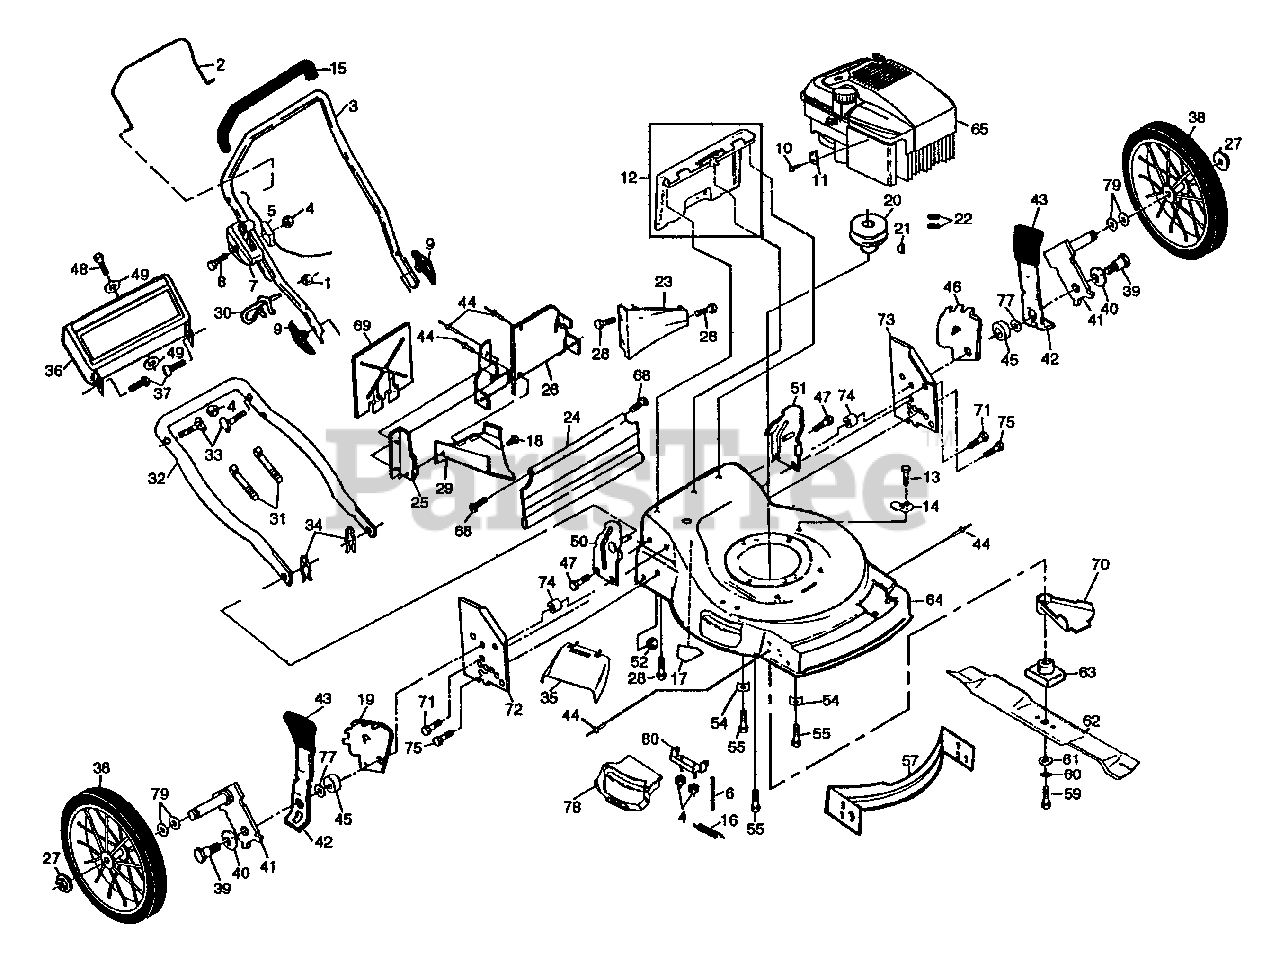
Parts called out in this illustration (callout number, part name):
1	Locknut
2	Control Bar
3	Upper Handle
5	Engine Zone Control Cable
7	Throttle Control
8	Hex Washer Head Screw 1/4-20 x 2-1/8
9	Handle Knob
10	Screw #10 x 5/8
11	Cable Clamp (Engine)
12	Rear Door Kit
15	Handle Grip
16	Hinge Spring
17	Danger Decal
19	Wheel Adjusting Bracket
20	Engine Pulley
21	Hi Pro Key #505
22	Set Screw 1/4-20 x 5/16
23	Rear Baffle
24	Rear Skirt
25	Side Baffle
26	Back Plate
27	Flanged Locknut
28	Screw Hex Head 1/4-20 x 1/2
29	Discharge Baffle
30	Rope Guide
31	Wire Tie
32	Lower Handle
33	Handle Bolt
34	Hairpin Cotter
35	Clip-on Discharge Deflector
36	Trim Plate Assembly
37	Push-in Fastener
38	Wheel & Tire Assembly
39	Shoulder Bolt
40	Spring Washer
41	Axle Arm
42	Selector Spring
43	Selector Knob
45	Spacer
46	Wheel Adjusting Bracket
47	Self-tapping Screw 5/16-18 x 3/4
50	Handle Bracket (Right)
51	Handle Bracket (Left)
52	Locknut 3/8-16
54	Engine Washer
55	Hex Head Thread Rolling Screw 3/8-16 x 1-1/8
57	Front Baffle
59	Hex Head Machine Screw 3/8-24 x 1-3/8 Gr. 8
60	Helical Lock Washer
61	Hardened Washer
63	Blade Adapter
64	Lawn Mower Housing Kit
65	Engine
68	Hinge Screw
69	Mulcher Plate
70	Debris Shield
71	Thread Cutting Screw 5/16 -18 x 1-1/5
72	Support Bracket (RH)
73	Support Bracket (LH)
77	Flat Washer
78	Combi-cut Door
79	Wave Washer
80	Hinge Bracket
